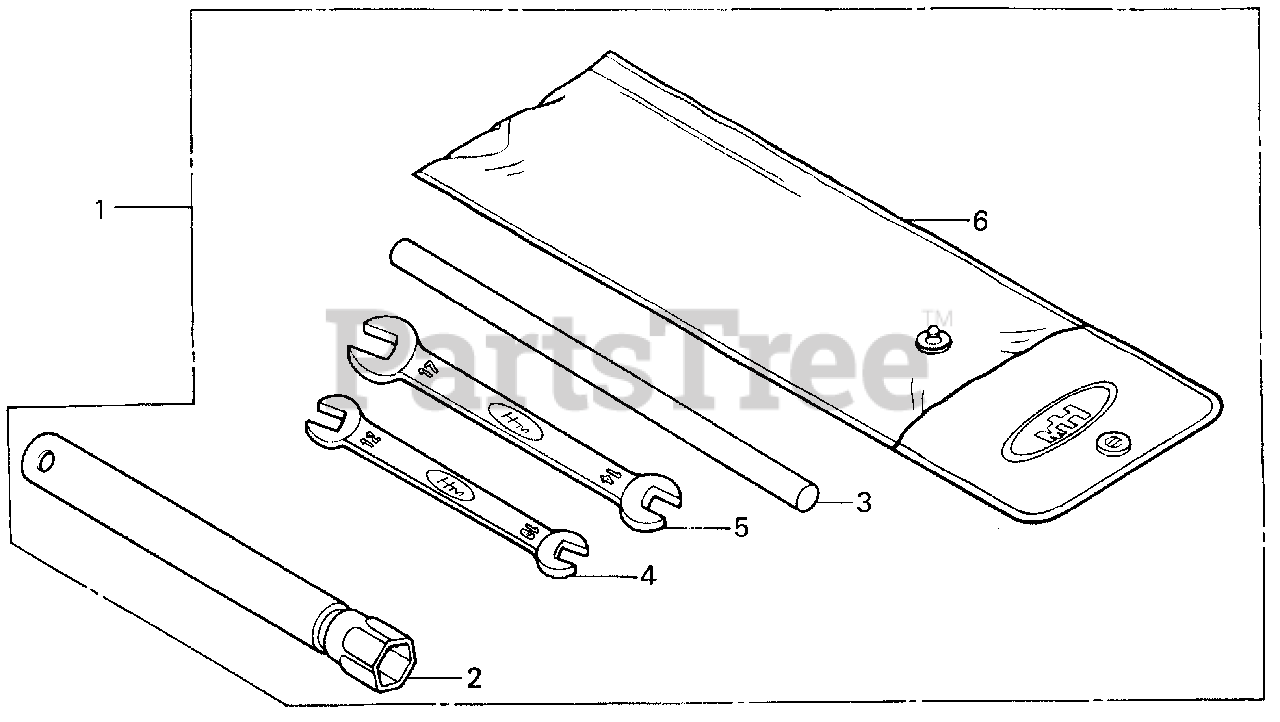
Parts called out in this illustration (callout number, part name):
1	TOOL KIT
2	WRENCH, SPARK PLUG
3	HANDLE, BOX WRENCH (NOT AVAILABLE)
4	WRENCH (10X12) (OPEN END)
5	WRENCH (14X17) (OPEN END)
6	BAG, TOOL (230MM)
